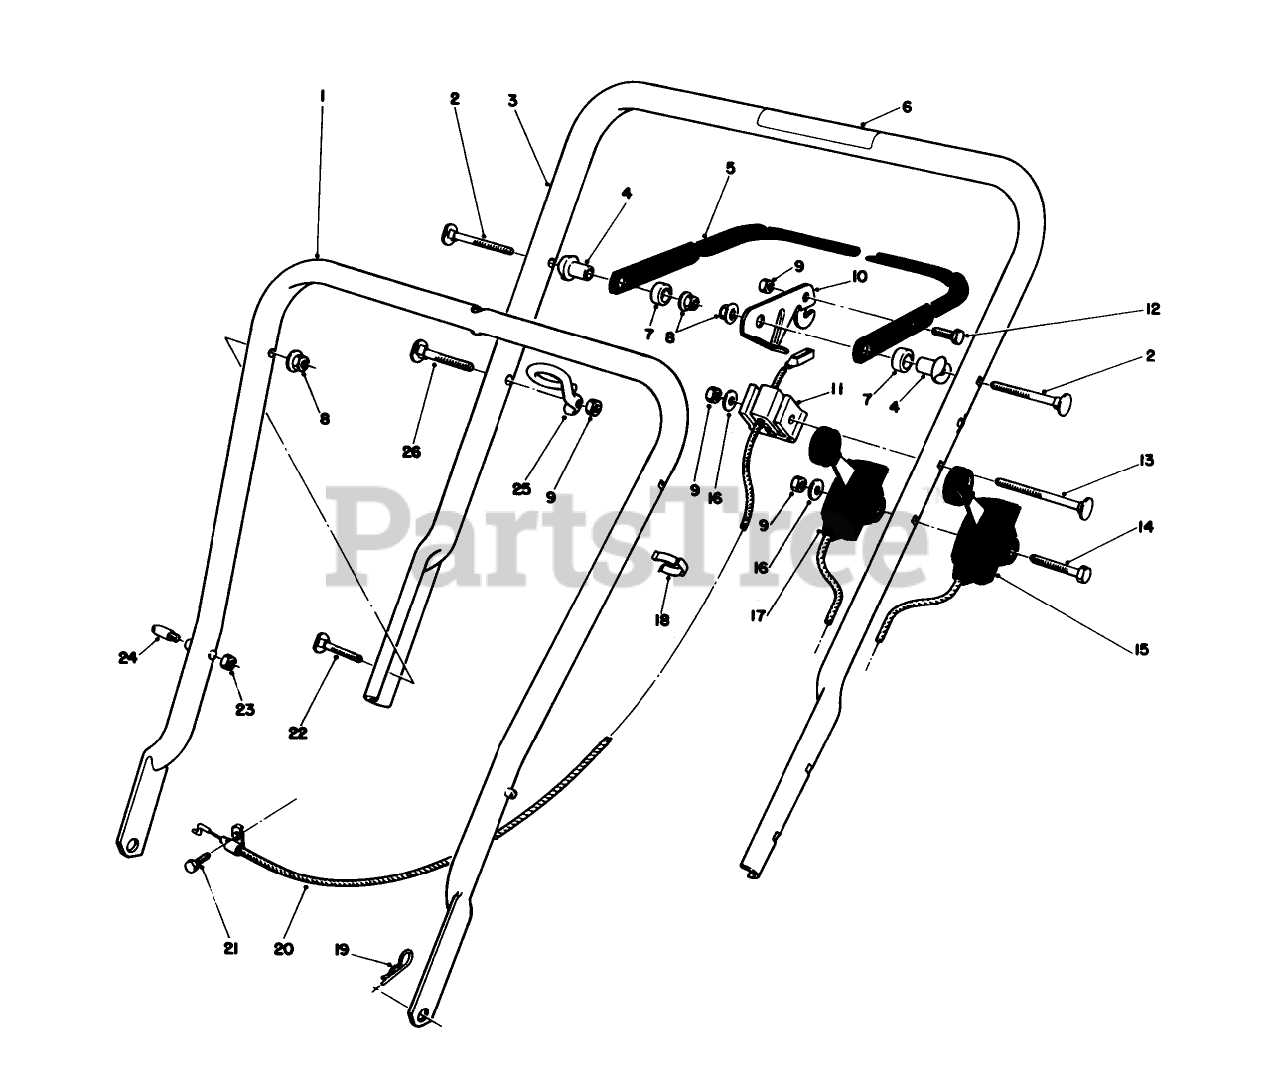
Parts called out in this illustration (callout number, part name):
1	LOWER HANDLE ASM
3	Handle-Upper (Incl. Ref. #6)
4	SPACER-SUPPORT
7	SPACER-NYLON
8	NUT-LOCK, NI
10	LEVER-CONTROL
11	SUPPORT-CABLE
12	SCREW-HH
13	HANDLE SCREW
14	SCREW-HH
15	TRACTION CABLE
16	WASHER-FLAT
17	THROTTLE CONTROL
18	BOWDEN CLIP
19	PIN-COTTER, HAIR
23	Locknut
24	HANDLE PIN
26	HANDLE SCREW
